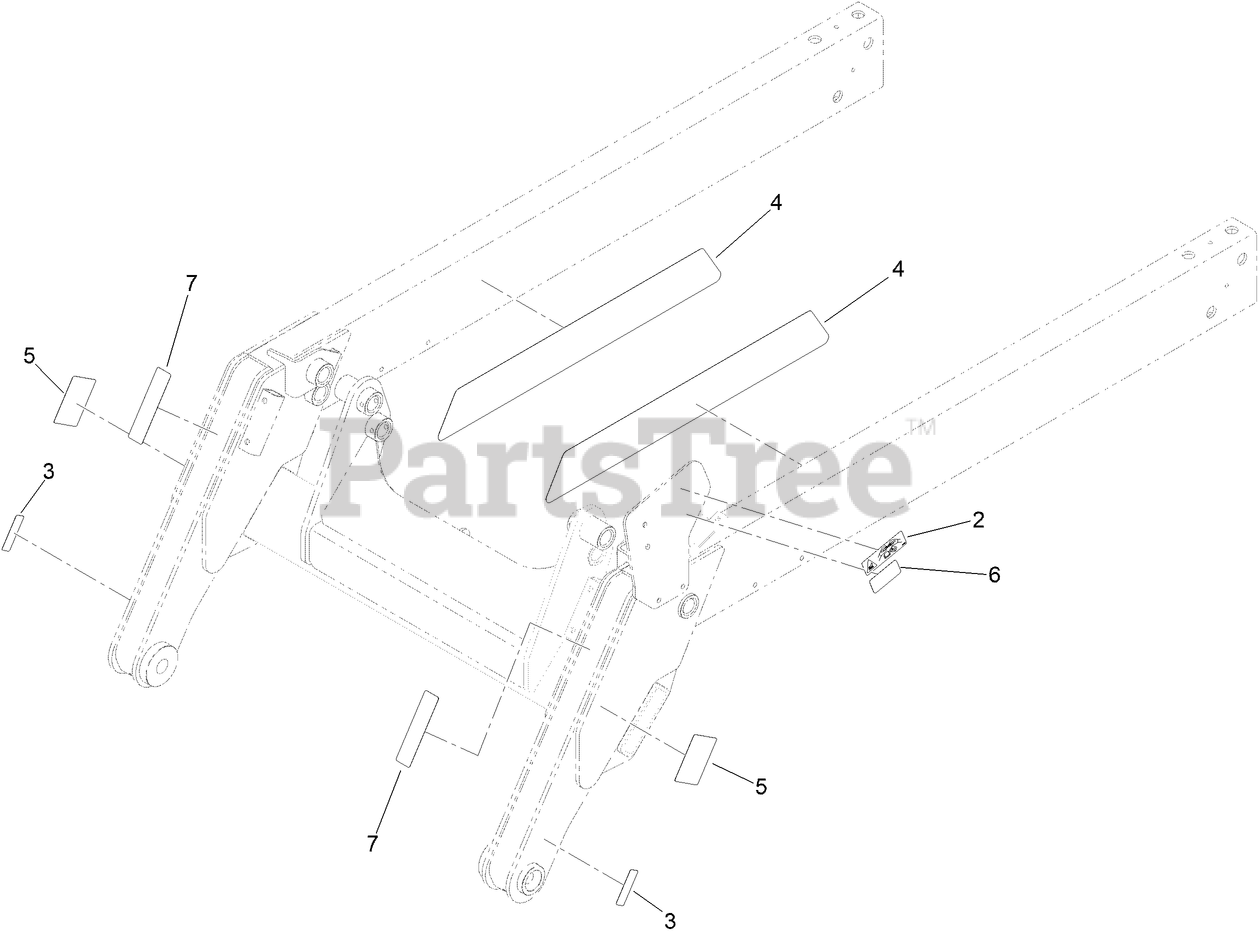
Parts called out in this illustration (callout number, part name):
2	DECAL-CAUTION
3	DECAL-WARNING, PINCH POINT
4	DECAL-EXTENSION
5	DECAL-WARNING, BUCKET
6	DECAL-WARNING, HYD PRESSURE
7	TAPE-REFLECTIVE
